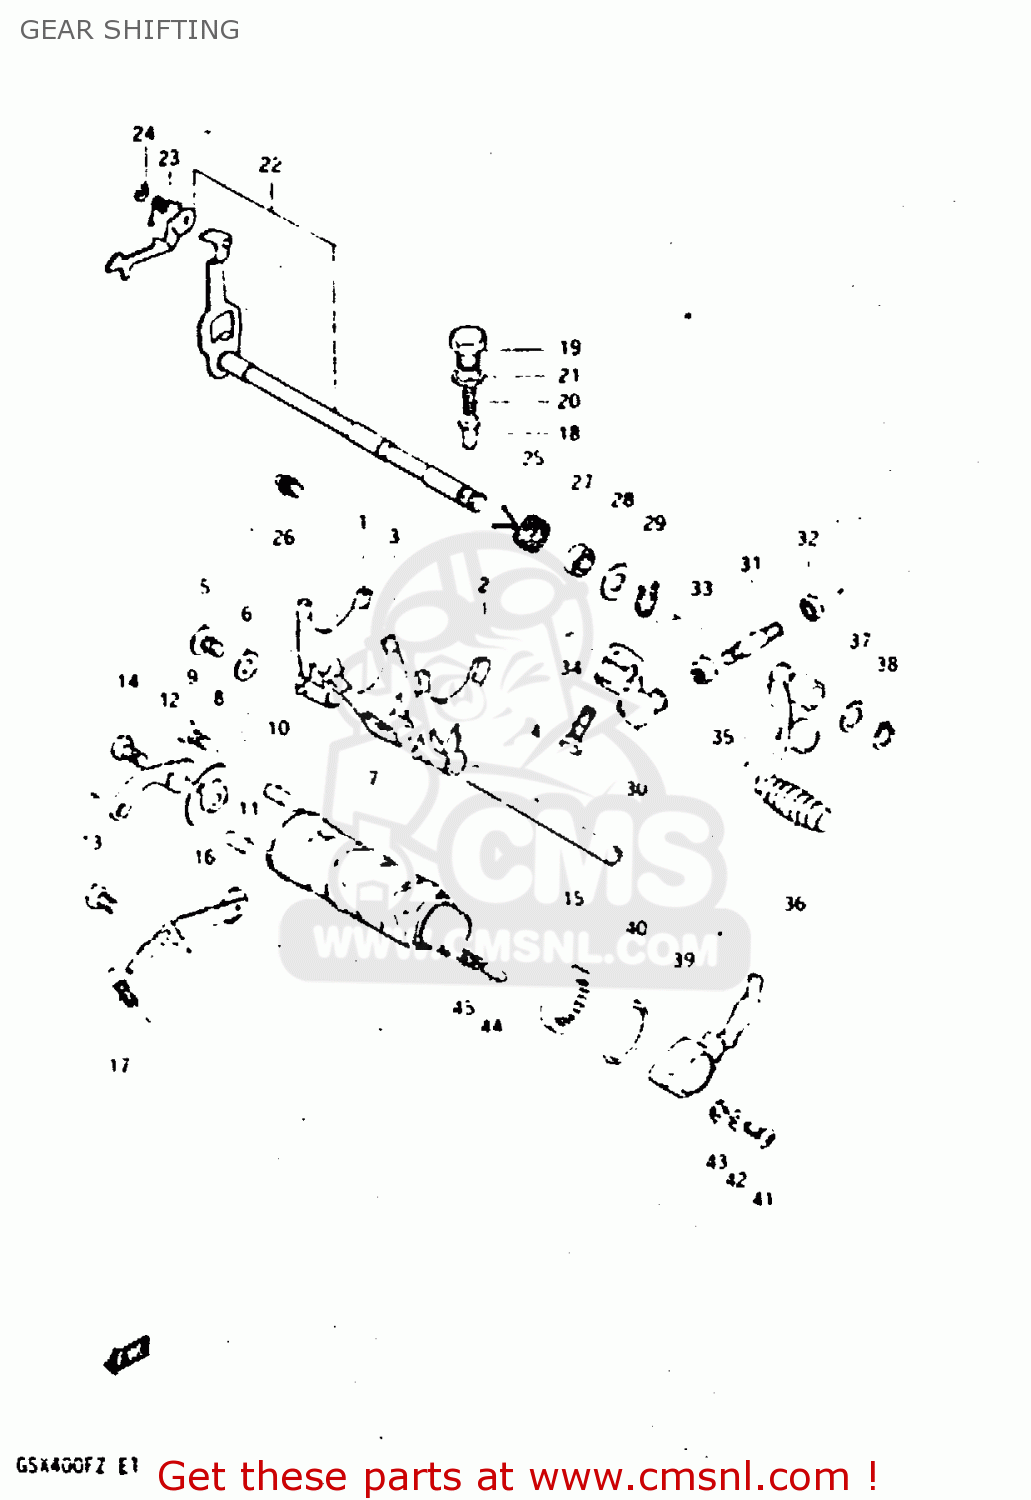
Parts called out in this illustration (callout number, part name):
1	FORK, GEAR SHIFTING
2	FORK, GEAR SHIFTING
3	FORK, GEAR SHIFTING
4	SHAFT,GEAR SHIFT FORK
5	SCREW
6	WASHER
7	CAM,GEAR SHIFT
8	RETAINER,GEAR SHIFT CAM DR PIN
9	SCREW
10	PIN
11	PIN(4X18.5)
12	GUIDE,GEAR SHIFTING CABLE
13	BOLT
14	BOLT, UPPER
15	BEARING(40X47X12)
16	STOPPER,GEAR SHIFT CAM NO.1
17	SPRING
18	STOPPER,GEAR SHIFT CAM NO.2
19	HOLDER,GEAR SHIFT CAM STOP SPR
20	SPRING
21	GASKET(14X19.2X2) (NAS)
22	SHAFT, GEAR SHIFTING
23	SPRING
24	E RING
25	SPRING
26	STOPPER,GEAR SHIFT CAM
27	OIL SEAL
28	WASHER (12.5X27X1.6)
29	SPRING,RETAINER
30	ARM,GEAR SHIFT LINK
31	ROD,GEAR SHIFT LINK
32	NUT
33	NUT
34	BOLT
35	LEVER ASSEMBLY,GEAR SHIFTING
36	RUBBER,GEAR SHIFT PEDAL
37	WASHER(12.5X20X1)
38	CIRCLIP
39	BASE ASSEMBLY,NEUTRAL SWITCH TERMINAL
40	O-RING (D:2.4 ID:26.2)
41	SCREW 5X20
42	LOCK WASHER
43	WASHER
44	PIN(5X15.5)
45	SPRING
